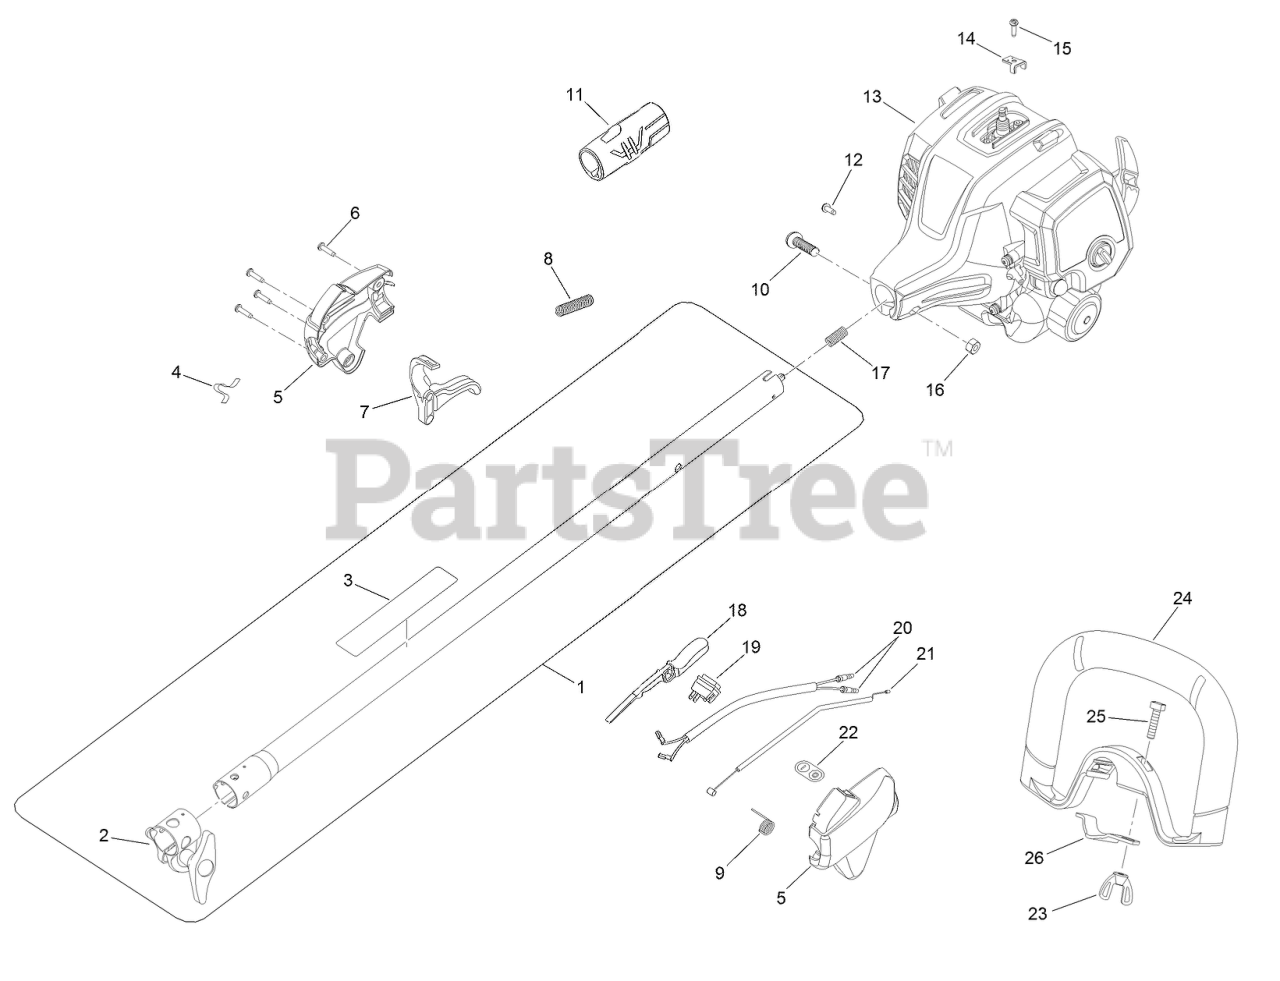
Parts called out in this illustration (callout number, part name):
1	UPPER SHAFT ASM
2	SHAFT CLAMP ASM
3	DECAL-WARNING
4	CLIP-STRAP, SHOULDER
5	CONTROL HANDLE ASM
7	TRIGGER
8	TUBE-CORRUGATED
9	SPRING-TRIGGER
11	GRIP-SHAFT, UPPER
13	Power Head ASM not serviced separately, for replacement parts see Power Head Components Assembly
14	CLAMP-CABLE, THROTTLE
16	NUT-HEX
17	SPRING-COMPRESSION
18	LOCK-TRIGGER
19	SWITCH-ON/OFF
21	CABLE-THROTTLE
22	LABEL-ON/STOP
23	NUT-WING
24	HANDLE-SHAFT, UPPER
26	CLAMP-HANDLE, UPPER SHAFT
